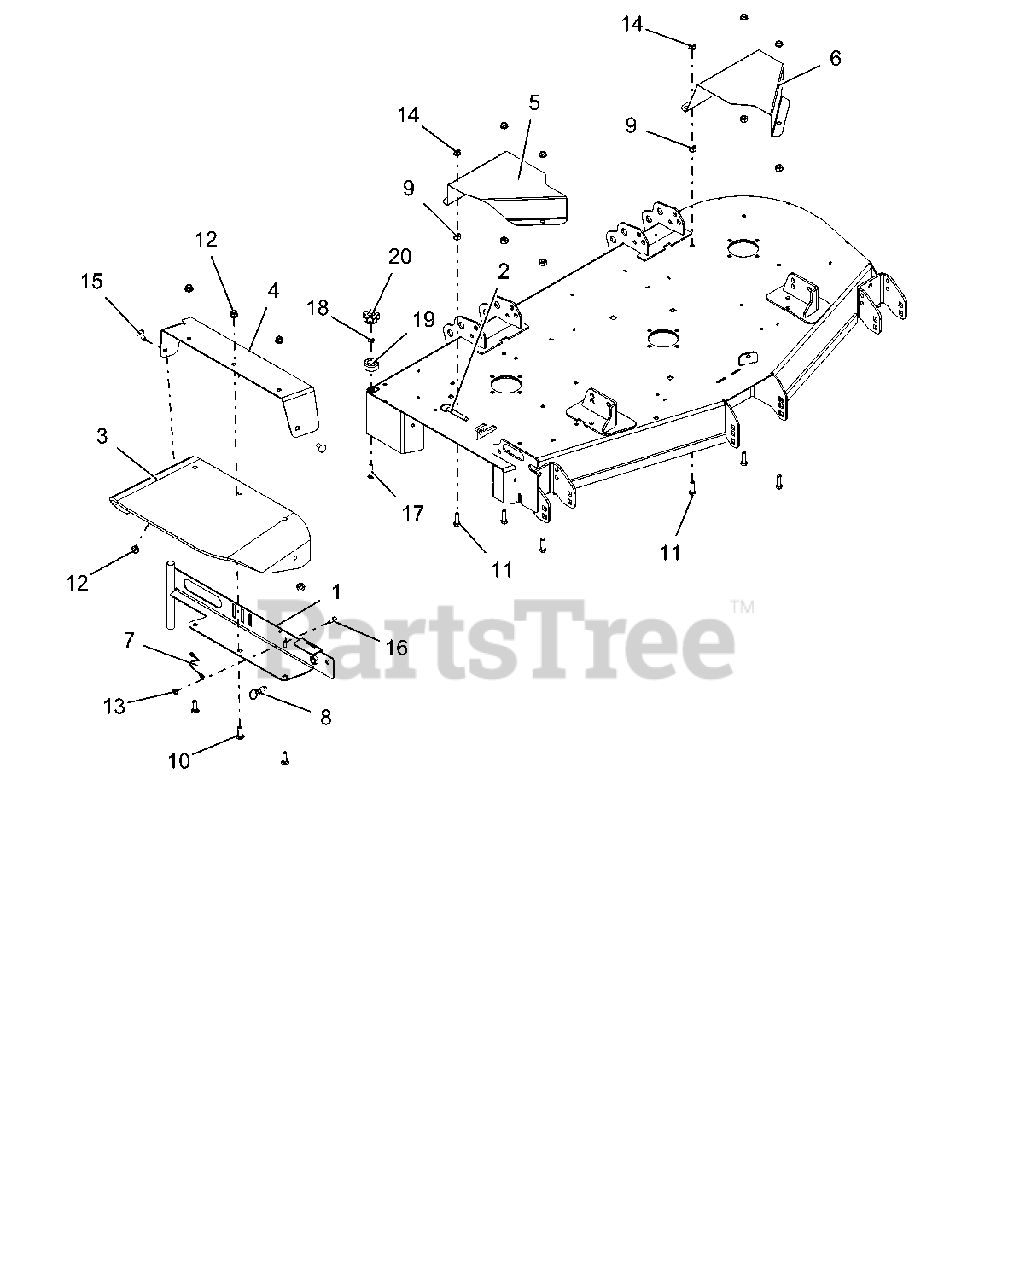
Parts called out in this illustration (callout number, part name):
1	WLDMT, DISCHARGE CHUTE 52"-60"
2	PIN, SPRING BALL .375OD X 1.50
3	CHUTE, RUBBER DISCHARGE
4	CHT SPPRT MTG BRKT W/SAFETY
5	GUARD, DECK 44"-52" RH
6	GUARD, DECK 44"-52" LH
7	CABLE, 6.0 LANYARD, NYLON
8	PULL PIN,.50-13THDX.310 PLNGR
9	NUT-HEAVY HEX .38-16 YWZC
10	@BLT-RDHDSQNK .38-16X1.25 G5YZ
11	@BLT-HEX .38-16X1.25 GR5 YWZC
12	@NUT-LK-NYL-FLG .38-16 YWZC
13	@NUT-LK-TOP-FLG .25-20 YWZC
14	@NUT-SPNLK-FLG .375-16 YWZC
15	@BLT-RDHDSQNK .38-16X1.00 G5YZ
16	@BLT-HEX .25-20X.75 GR5 YWZC
17	@BLT-RDHDSQNK .31-18X1.50 G5YZ
18	@NUT-LK-CTR .31-18 YWZC
19	BUMPER,RECESSED1.50X.63 W/.31
20	KNOB-CLAMPING, .312-18 NYLOC
